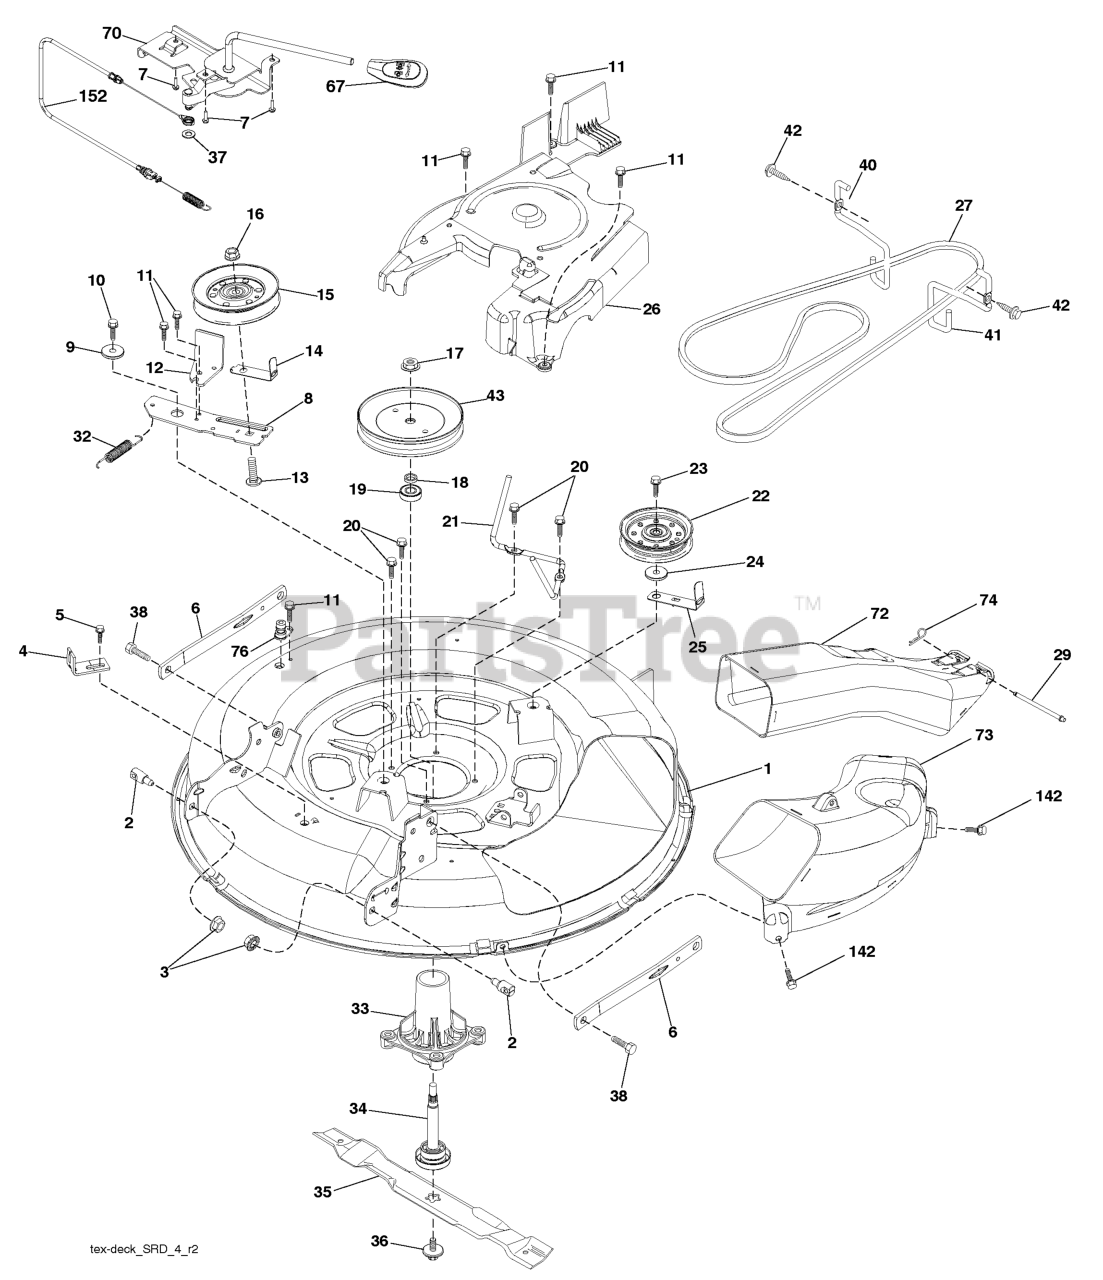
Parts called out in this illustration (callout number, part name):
1	DECK.WELDMENT.30"SRD.BLACK
2	STUD.FASTNER.W/ANTI-ROTATE
3	NUT LOCK HEX FLANGE 5/16-18
4	BRACKET.CLUTCH.CABLE
5	BOLT.5/16HEX.WHS.HD
6	ARMS.SUSP.MOWER.REAR.SRD
7	SCREW.#10 X 0.750.BOS
8	ARM.IDLER.30"SRD
9	SPACER.RETAINER
10	SCREW 3/8-16X1
11	SCREW.1/4-20X5/8
12	RP ARM.BRAKE.MOWER.38"LH.TEX
13	BOLT.3/8-16X1.50
14	KEEPER, BELT IDLER
15	PULLEY.IDLER.4.25
16	NUT LOCK FLG 3/8-16 UNC
17	NUT.FLANGE.LOCK.TOP
18	WASHER.SPACER.MANDREL
20	SCREW, WASHER HEAD
21	KEEPER.BELT.MANDREL.30"
22	PULLEY.IDLER.FLAT.UNPLATED
23	SCREW LT
24	WASHER
25	KEEPER.BELT.30"SRD
26	COVER.ASM.MANDREL.30"
27	BELT
29	PIN.HINGE.30".SRD
32	SPRING RETURN
33	RP.HOUSING.MANDREL.4PT.
34	SHAFT.ASM.MDRL.N/GREASE.38
35	BLADE.MOWER.BAGGING.30"
36	BOLT.WASHER.ASM.7/16-2
37	WASHER
38	BOLT.SHOULDER
40	KEEPER.BELT.ENGINE.LH.LT.SRD
41	KEEPER.BELT.ENGINE.RH.LT.SRD
42	SCREW, 3/8-16X3/4
43	PULLEY, MANDREL 6.5 PD
67	HANDLE.CLUTCH.CABLE.LT
70	CLUTCH.ASM.MANUAL.LT.PRED
72	CHUTE.UPPER.SRD.30R"
73	CHUTE.LOWER.SRD.30R"
74	RETAINER-SPRNG RB
76	PORT.WASHOUT
142	SCREW, 3/8-16X3/4
152	CLUTCH CABLE
